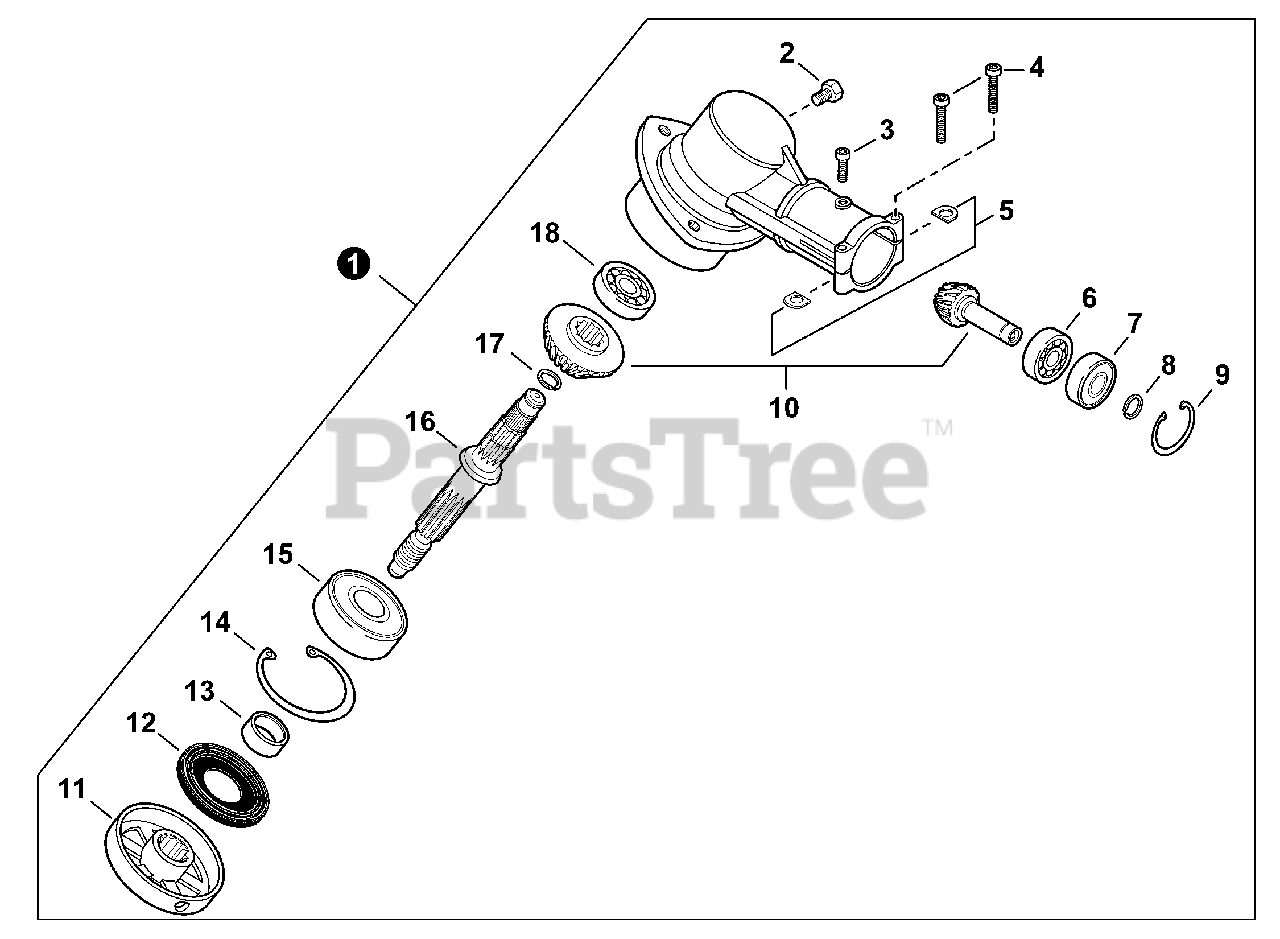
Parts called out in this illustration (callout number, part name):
1	GEAR CASE ASSY
2	BOLT M8×1.25
3	BOLT, TORX 5×10
4	BOLT, TORX 5×25
5	D-WASHER
6	BEARING, BALL 6900
7	BEARING, BALL 6900-Z
8	RING, SNAP Ø10
9	RING, SNAP Ø22
10	GEAR SET
11	PLATE, ADAPTOR - UPPER
12	SEAL, OIL 22
13	SPACER 11.8×15×9
14	RING, SNAP Ø32
15	BEARING, BALL 6201
16	SHAFT, GEAR
17	RING, SNAP Ø12
18	BEARING, BALL 609
